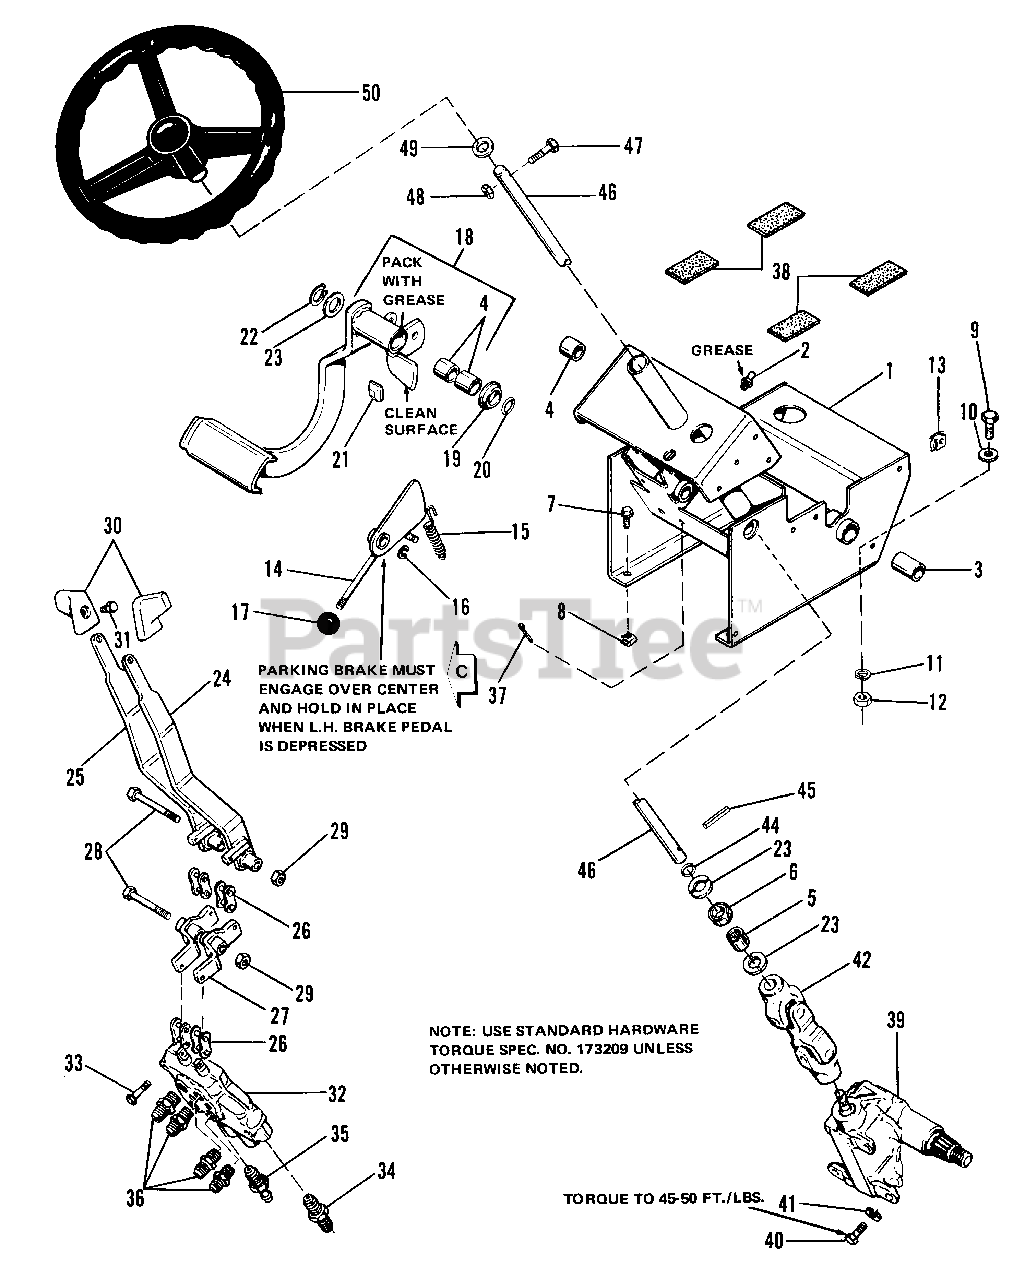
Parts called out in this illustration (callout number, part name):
1	SUPPORT ASSY
2	FITTING, Lube, 1/4-28
3	BUSHING, Sleeve
4	BEARING, Sleeve
5	BEARING, Needle
6	BEARING, Roller
7	SCREW, Self Tapping, 5/16 x 7/8
8	NUT, Speen, Tinner.
9	CAPSCREW, Hex, 5/16-18 x 3/4
10	WASHER, Plain, 3/8
11	LOCKWASHER, 36
12	NUT, Hex, 5/16-18
13	NUT, Retainer, 1/4-20
16	RING, Retaining
18	LEVER ASSY
20	RING, Retaining
22	RING, Retaining
24	LEVER ASSY
25	LEVER ASSY
26	LINK, Connect.
27	BELLCRANK ASSY
28	CAPSCREW, Hex, 3/8-16 x 2-3/4
29	NUT, Hex, Lock, 3/8-16 x 2-3/4
31	SCREW, Taptite, 1/4-20 x 3/4
32	VALVE, Hydro.
33	SCREW, Taptite
34	CONNECTOR, Male
35	CONNECTOR, Hose
36	CONNECTOR, Male
37	PIN, Cotter, 5/32 x 1
38	GASKET, Felt
39	GEAR ASSY, Steering
40	CAPSCREW, Hex, 7/16-14 x 1
41	LOCKWASHER, 7/16
44	RING, Retaining
45	PIN, Spring, 3/8 x 1-1/4
47	CAPSCREW, Hex, 5/16-18 x 1-1/4
48	LOCKNUT, Hex, Flange, 5/16-18
49	WASHER, Rubber
50	WHEEL, Steering
